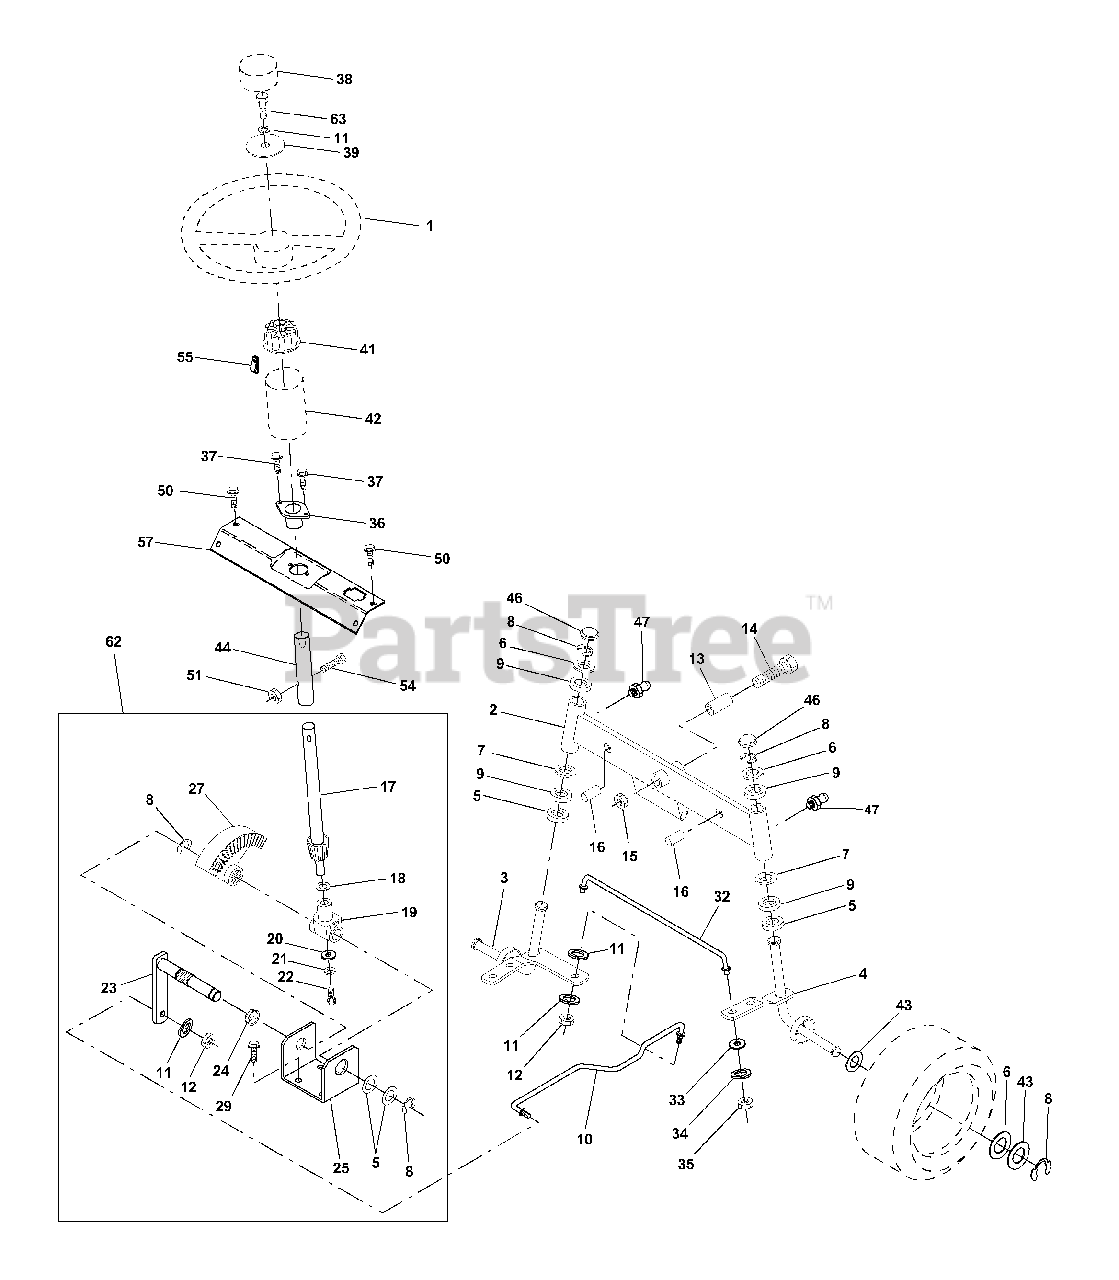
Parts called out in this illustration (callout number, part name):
1	Wheel Steering Auto Grey
2	Axle Asm Fr LT W/gzks 38/42
3	Spindle Asm LH
4	Spindle Asm RH
5	Washer, Thrust .75 x 1.230
6	Washer 25/32 X 1-5/8 X 16 Ga
7	Washer 27/32 X 1-1/4 X 16 Ga
8	Ring Klip #t5304-75
9	Bearing Col Strg Blk
10	Link Drag Sol Ball Jt 20 064
11	Washer Lock Hvy Hlcl Spr 3/8
12	Nut Fin Hex 3/8-24 Unf
13	Spacer Bearing Axle Front
14	Bolt Hex 5/8-11 Unc X 3-1/2
15	Nut Lock Flange 5/8-11 Unc
16	Pin Axle 5/8 X 1 55/1 54 Lg
17	Shaft Asm Strg Private Label
18	Washer Thrust 515x 750x 033
19	Support Shaft
20	Washer Shim 1/4 X 5/8 X 062
21	Washer Lock Hvy Helical 1/4
22	Screw Cap Sckt Hd Phos & Oil
23	Shaft Asm Pittman
24	Nyliner Snap In
25	Bracket Steering
27	Gear Sector
29	Screw Thdrol 3/8-16x3/4 Ty-tt
32	Rod Tie Ball Jt Sol 19.75 Elec.
33	Washer 11/32 x 3/4 x 16 Ga.
34	Washer Lock Hvy HLCL SPR 5/16
35	Locknut 5/16-24 UNF 3847
36	Bushing Strg
38	Insert Cap Strg Wh Au Husq Gry
39	Washer 13/32 X 2-3/8 X 8 Ga
41	Adaptor Wheel Strg
42	Boot Steering Shaft
43	Washer 25/32 X 1 1/4 X 16 Ga
44	Extention Steering
46	Cap Spindle Fr Top Blk
47	Fitting Grease
50	Screw Hex Wsh Thdrol 1/4-20 x 3/4
51	Nut Lock Hex w/Ins 5/16-18
54	Bolt Fin Hex 5/16-18 Unc x 1-1/4
55	Clip Tinnerman
57	Support Shaft Steering
62	Kit, Steering Assembly
63	Bolt Fin Hex 3/8-16unc x 1 Gr. 5
